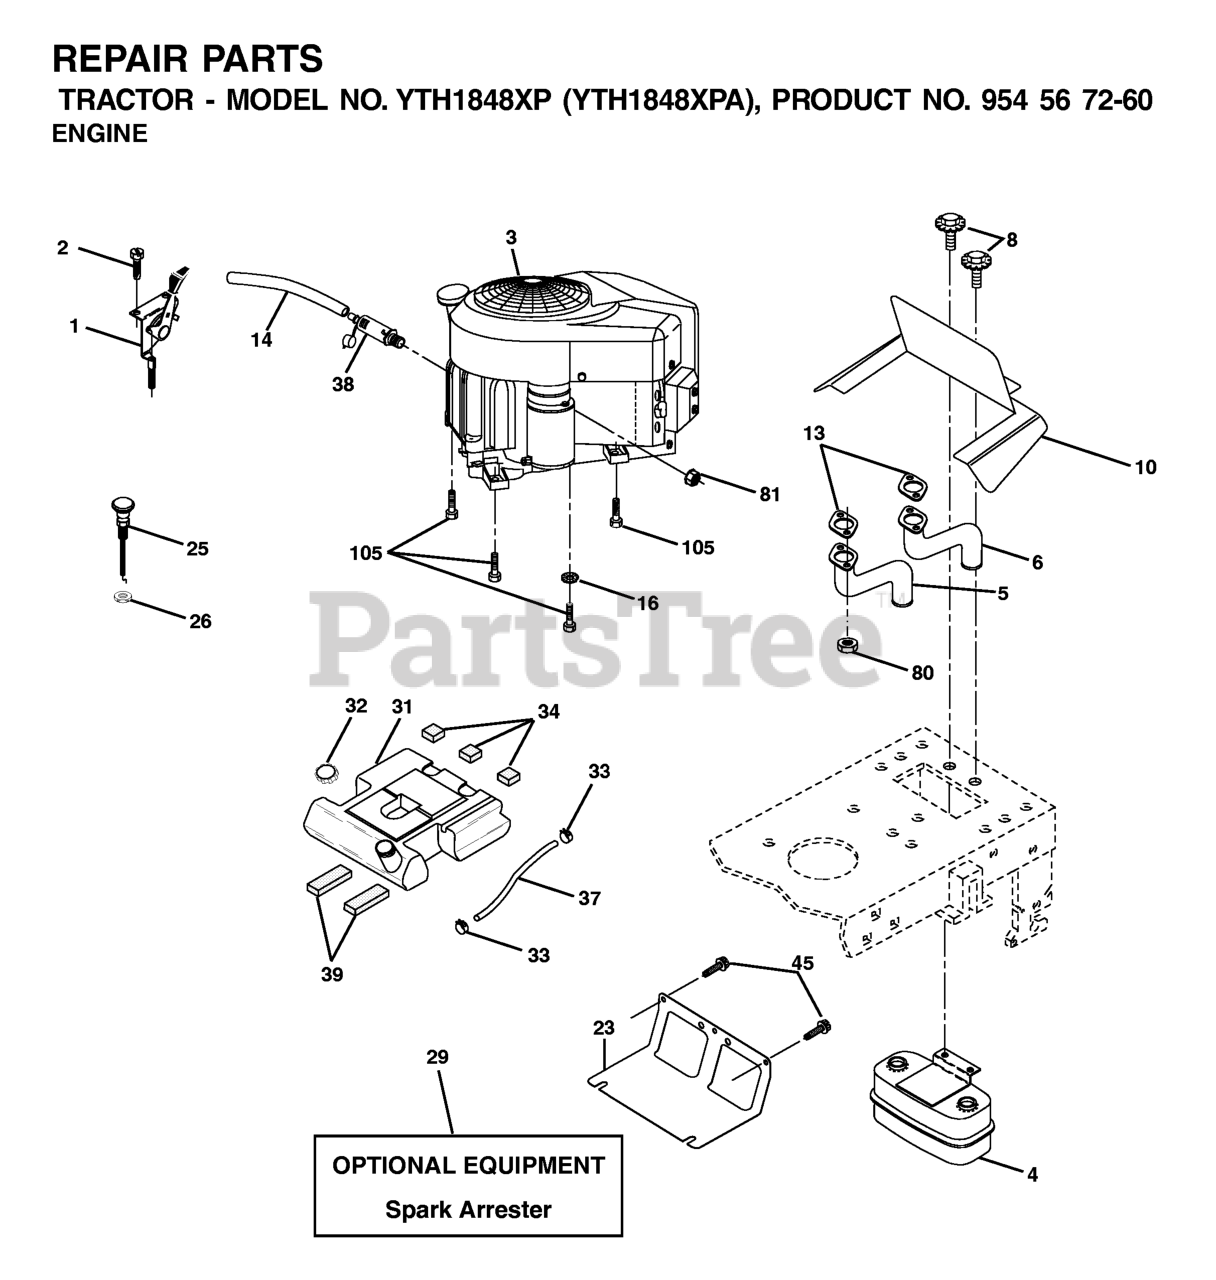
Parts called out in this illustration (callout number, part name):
1	CONTROL, THROTTLE
2	SCREW LT
4	MUFFLER.TWIN.CYL.LOW.TONE
5	EXHAUST.TUBE.LH.KAWASAKI.
6	EXHAUST.TUBE.RH.KAWASAKI.
8	BOLT.5/16-18UNCX3/4 W/SEMS.BLK
10	RP SHIELD HEAT MUFFLER
14	TUBE, DRAIN OIL ASM.
16	LOCKWASHER
23	SHIELD.BROWNING.DBR.GUARD
25	CHOKE CONTROL
26	Nut Keps 3/8 - 24 UNF
29	KIT.SPARK ARRESTOR 794945 B&S
31	TANK.FUEL(3.5.GAL)
32	FUEL CAP
33	HOSE CLAMP
34	PAD-SPACER LT
37	REPL BY 532 00 85-43
39	PAD IDLER TI
45	SCREW, 3/8-16X3/4
80	FLANGE NUT
81	NUT
105	SCREW 3/8-16X1
